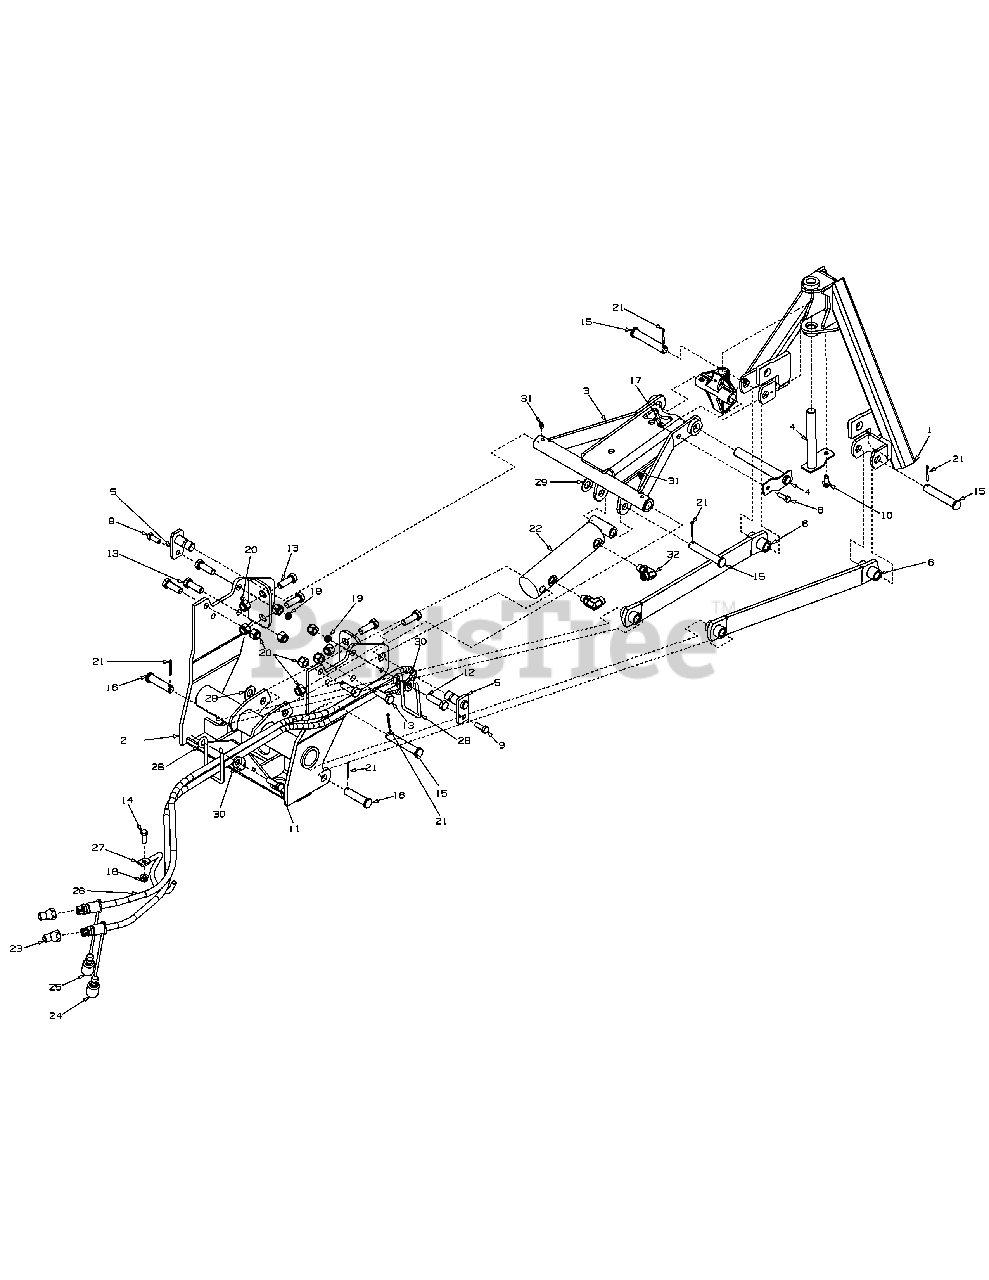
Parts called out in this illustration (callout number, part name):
1	Frame Assembly, Hitch
2	Brace, Front Hitch
4	Pin, Front Hitch
5	Pin, Hitch Pivot
6	Arm, Front HItch
7	Housing, Pivot
8	Screw, Hex Cap, 5/16-18 x 1.0 Gr5
9	Screw, Hex, 3/8-16 x 1.00
10	Scrw, Hx Wsh. Hd Tapp, 5/16-18 x .75
11	Screw, Hex Cap, M10-1.5 x 35 Gr8
12	Screw, Hex Cap, 1/2-13 x 1.75 Gr5
13	Screw, Hex Cap, 1/2-13 x 1.5 Gr5
14	Screw, Hex, M8-1.25 x 25.0
15	Pin, Clevis, .625 x 3.45
16	Pin, Clevis, .625 x 2.313
17	Nut, Hx Insert Flnge Lck, 3/8-16 GrF
18	Nut, Flange Lock M8-1.25
19	Nut, Insert Jam Lock, 3/8-16 Gr5
20	Nut, Hex Insert Lock, 1/2-13 GrB
21	Pin, Cotter, 1/8 x 1.25
22	Cylinder, Hitch Lift
23	Coupling, Hydraulic Male
24	Plug, Female Hyd. Coupler, Blue
25	Plug, Female Hyd. Coupler, Red
26	Hose, Hydraulic, 60"
27	Rod, Hose Support
28	Rod, Hose Support
29	Washer, Flat, .65 x 1.25 x .075
30	Washer, Flat, .51 x 1.0 x .125
31	Fitting, Lube
32	Fitting, 90 Degree, 3/8FS x 3/8 Orb
